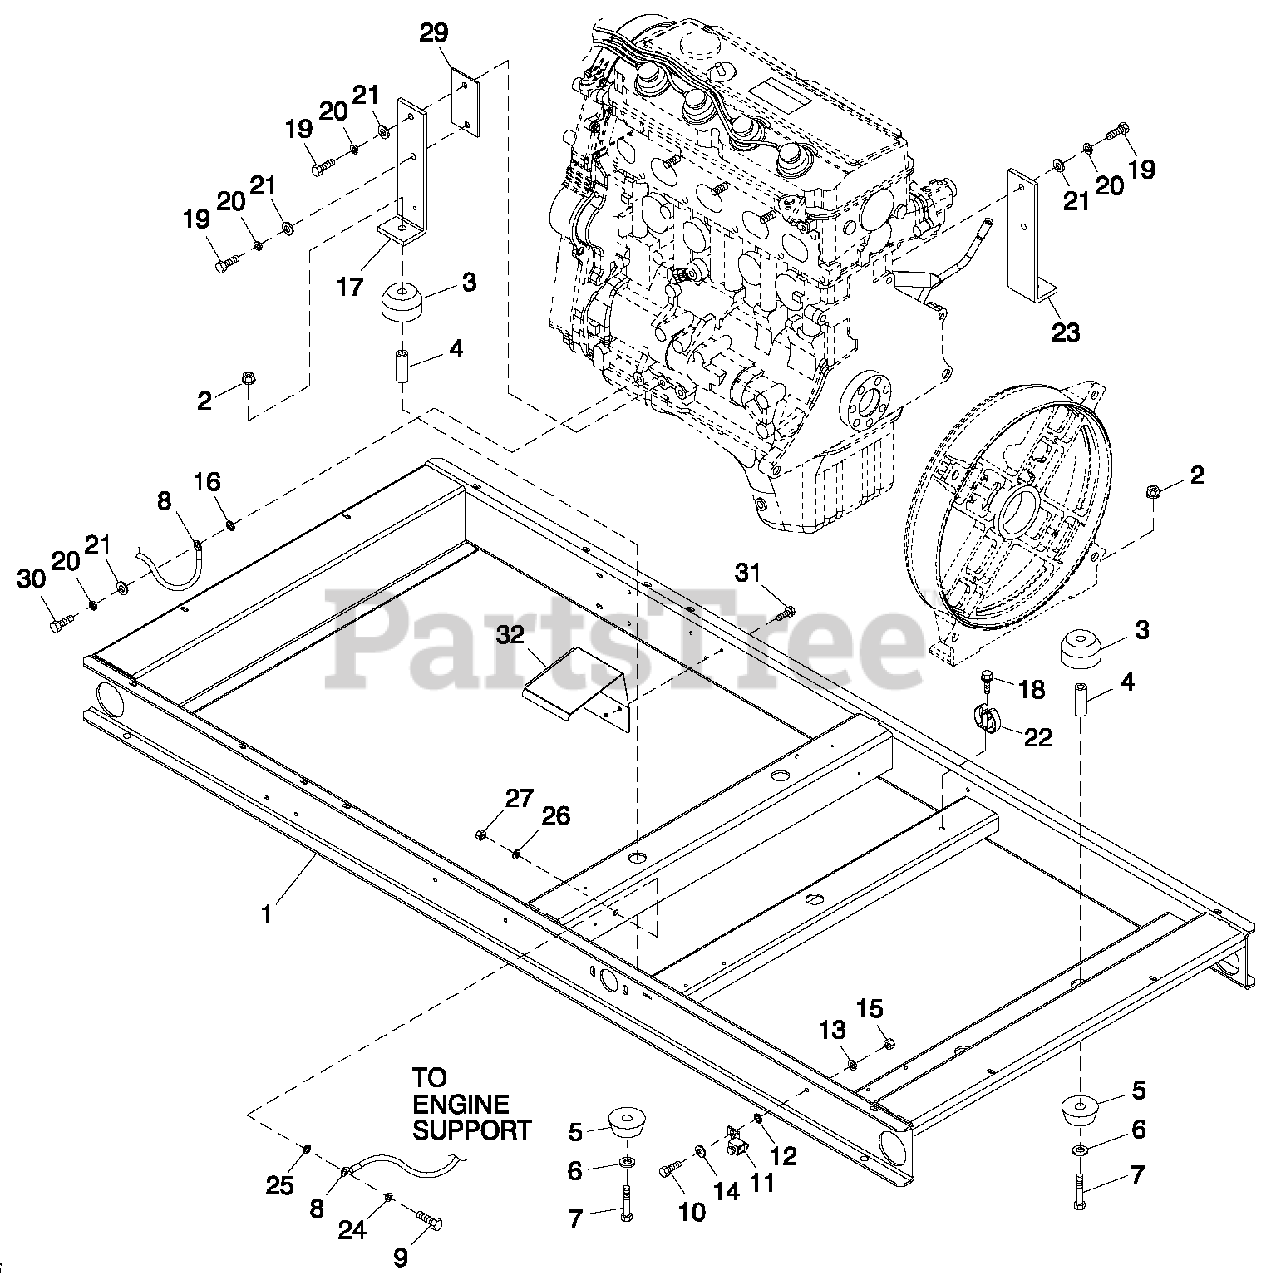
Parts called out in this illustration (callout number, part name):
1	WELDMENT FRAME 2.4L C2
2	NUT FLANGED HEX M12-1.75
3	DAMPENER VI B RATION 40 BLUE
4	SPACER .49 X .62 X 1.87 PWDR/ZNC
5	DAMPENER VI B RATION
6	WASHER FLAT M12
7	SCREW HHC M12-1.75 X 80 G8.8
8	ASSY WIRE 14.00"
9	SCREW HHC M8-1.25X 30 G8.8
10	SCREW HHC M6-1.0X 16 G8.8
11	LUG SLDLSS #2-#8X 17/64 CU
12	WASHER LOCK SPECIAL 1/4"
13	WASHER LOCK M6-1/4
14	WASHER FLAT M6-1/4 ZINC
15	NUT HEX M6 -1.0G8YEL CHR
16	WASHER SHAKEPROOF INT 3/8
17	SUPPORT LH ENGINE 2.4L
18	SCREW HHTT M4-0.7X8BP
19	SCREW HHC M10-1.25 X 30 G8.8
20	WASHER LOCK 7/16
21	WASHER FLAT 3/8-M10 ZINC
22	SPRING CLIP HOLDER .37-.62
23	SUPPORT RH ENGINE 2.4L
24	WASHER LOCK M8-5/16
25	WASHER LOCK SPECIAL 5/16
26	WASHER FLAT 5/16-M8 ZINC
27	NUT HEX M8-1.25 G8 CLEAR ZINC
29	SPACER ENGINE MOUNT (2.4L G1)
30	SCREW HHC M10-1.25 X 25 C8.8
31	SCREW HWHT M6-1 X 16 N WA Z/JS
32	HEAT SHIELD 2.4L G2
